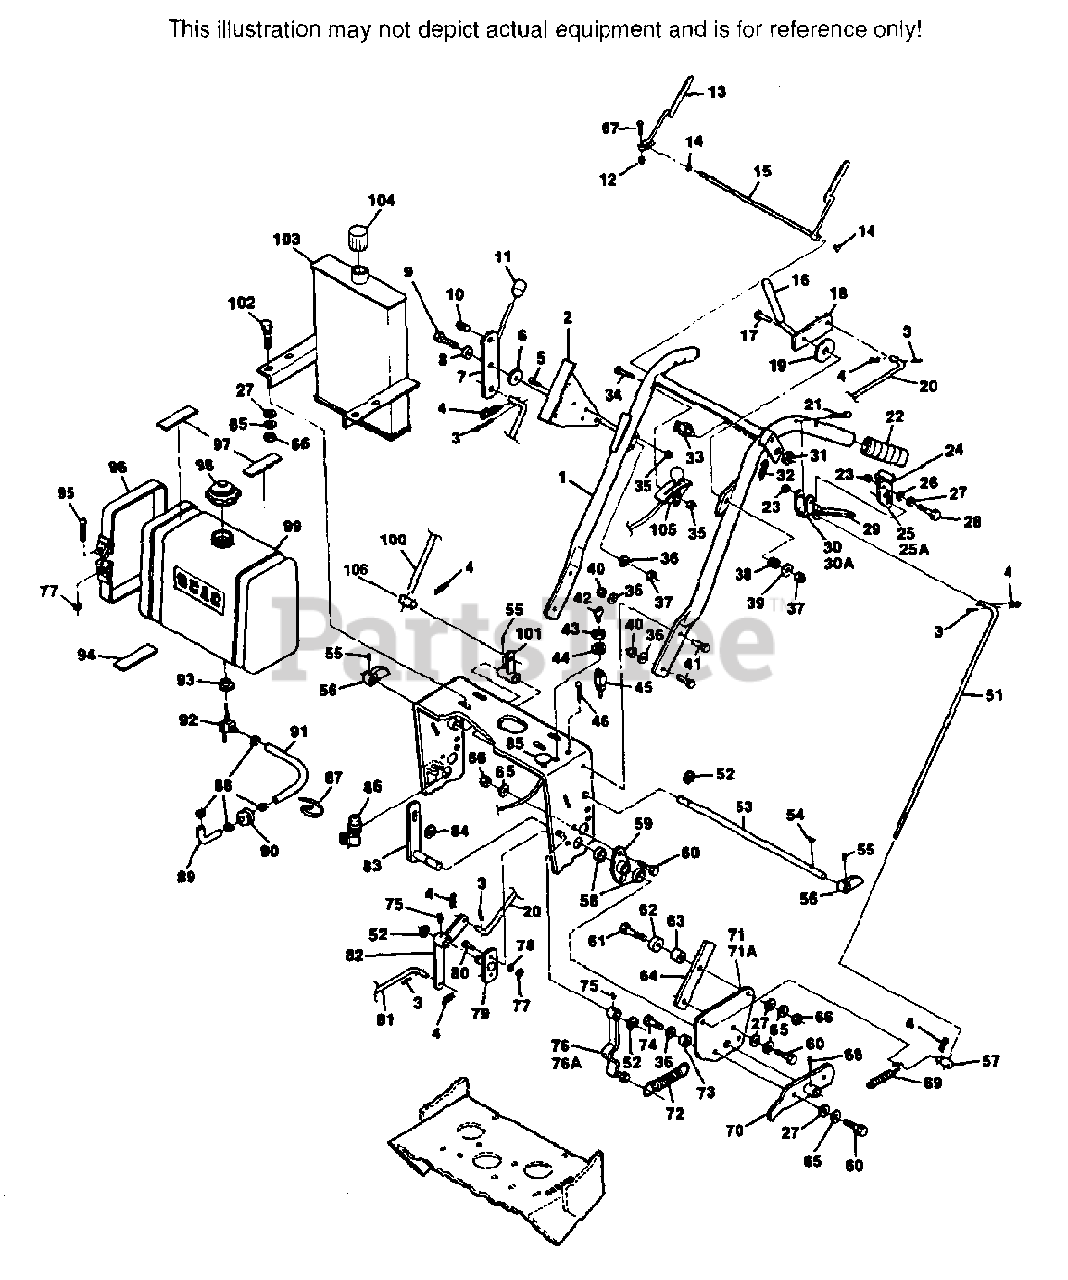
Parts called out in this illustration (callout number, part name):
1	HANDLE ASSEMBLY(FOR 16")
1	HANDLE ASSEMBLY(FOR 20")
2	QUADRANT, SPEED CONTROL
4	HAIR PIN, SMALL
5	CAPSCREW, 1/4-20 X .75 FLAT HD. HEX SOCKET
7	SPEED ADJUSTMENT LEVER
8	BUSHING SPEED ADJUSTMENT LEVER
10	BALL PLUNGER
11	KNOB, SPEED ADJUSTMENT LEVER
12	NUT, 5/16-18 ELASTIC STOP
13	OPERATOR PRESENCE, HAND GRIP-RH
14	BUSHING, CONTROL ROD
15	OPERATOR PRESENCE HAND GRIP & ROD - LH(FOR
15	OPERATOR PRESENCE HAND GRIP & ROD - LH.(FOR
16	GRIP, CUTTER DECK ENGAGE
18	BLADE CLUTCH LEVER ASSY.(INCLUDES GRIP)
19	FLAT WASHER, 3/8 X 2 X 16 GA.
20	ROD, BELT CLUTCH - CUTTER
21	CARRIAGE BOLT, 5/16-18 X 2-1/2, RD. HD. SQ.
22	GRIP, HANDLE
23	HEX NUT, 5/16-18, ELASTIC STOP
24	GRIP, NEUTRAL LATCH - RH
24	GRIP, NEUTRAL LATCH - LH
25	NEUTRAL LATCH - RH(INCLUDES GRIP)
25A	NEUTRAL LATCH - LH(INCLUDES GRIP)
26	CURVED SPRING WASHER
29	GRIP, STEERING CONTROL
30	STEERING CONTROL LEVER - RH(INCLUDES GRIP)
30A	STEERING CONTROL LEVER - LH(INCLUDES GRIP)
31	HEX NUT, 9/16-18 SPRING STEEL
32	SPRING, GRIP RETURN
33	SWITCH, INTERLOCK(GOLD COLORED)
35	HEX NUT, 1/4-20 ELASTIC STOP
37	HEX NUT, 3/8-16 ELASTIC STOP
38	SPRING, COMPRESSION
39	FLAT WASHER, 25/64 X 15/16 X 12 GA.
40	HEX NUT, 3/8-16 ELASTIC STOP
42	KEY, IGNITION
43	HEX NUT, 5/8-32
44	LOCKWASHER, 5/8 INTERNAL TOOTH
45	SWITCH, IGNITION
48	LOCKWASHER, #10 EXTERNAL TOOTH
50	MACHINE SCREW, #10-32 X 1/2 PHILLIPS
51	CONTROL ROD, STEERING
52	RETAINING RING, 5/8 EXT. - "E"
53	JACKSHAFT, SPEED CONTROL(FOR 16")
53	JACKSHAFT, SPEED CONTROL(FOR 20")
54	KEY, 1/8 X 1/2 WOODRUFF #3
55	SETSCREW, HEX SOCKET KNURLED CUP PT.,
56	CAM, SPEED CONTROL(INCLUDES SETSCREW)
57	SWIVEL JOINT, STEERING ROD
58	BUSHING
59	PIVOT, PUMP CONTROL SHAFT(INCLUDES BUSHINGS
61	BOLT, HEX HD., 5/16-18 X 1-3/4 FULL THREAD
62	BEARING, SPEED CONTROL
63	SPACER, SPEED CONTROL BEARING
64	BAR, SPEED CONTROL ADJUSTMENT
68	DRIVE PIN, 5/32 X 7/8 TYPE U
69	SPRING, SPEED CONTROL
70	HANDLE, NEUTRAL ADJUSTMENT
71	BELLCRANK, LH CONTROL
71A	BELLCRANK, RH CONTROL
72	SPRING, NEUTRAL RETURN
73	BEARING, NEUTRAL RETURN
75	GREASE FITTING, STRAIGHT 1/4-28
76	NEUTRAL CAM, RH(INCLUDES GREASE FITTING)
76A	NEUTRAL CAM, LH(INCLUDES GREASE FITTING)
79	BELLCRANK PIVOT
81	ROD, BLADE CLUTCH - LOWER
82	BELLCRANK, CUTTER ENGAGE(INCLUDES GREASE
83	SHAFT, LH PUMP CONTROL
84	RETAINING RING, 1/2" EXT. - "E"
86	SWITCH, NEUTRAL
87	CABLE TIE
88	CLAMP, FUEL HOSE
89	FUEL HOSE, SHORT 7/32 ID X 3-1/2(KA ONLY)
90	FUEL FILTER
91	FUEL HOSE, 1/4 ID X 20
92	VALVE, FUEL SHUT-OFF
93	BUSHING
94	PAD, RUBBER - FUEL TANK - LOWER
95	MACHINE SCREW, 1/4-20 X 2 ROUND HD. SLOTTED
96	STRAP, FUEL TANK
97	PAD, RUBBER - FUEL TANK - UPPER
98	FUEL TANK CAP
99	FUEL TANK ASSEMBLY(INCLUDES ITEMS 92,93,)
100	ROD, TRACTION CONTROL
101	BELLCRANK, SPEED CONTROL
102	CARRIAGE BOLT, 5/16-18 X 1 RD. HD. SQ. NK.
103	OIL RESERVOIR(FOR 16") INCLUDES DECAL
103	OIL RESERVOIR(FOR 20") INCLUDES DECAL
104	CAP, OIL RESERVOIR
105	THROTTLE CONTROL
106	SWIVEL JOINT, SPEED CONTROL ROD
NS	WIRE HARNESS
NS	WIRE HARNESS ADAPTER - KAWASAKI
